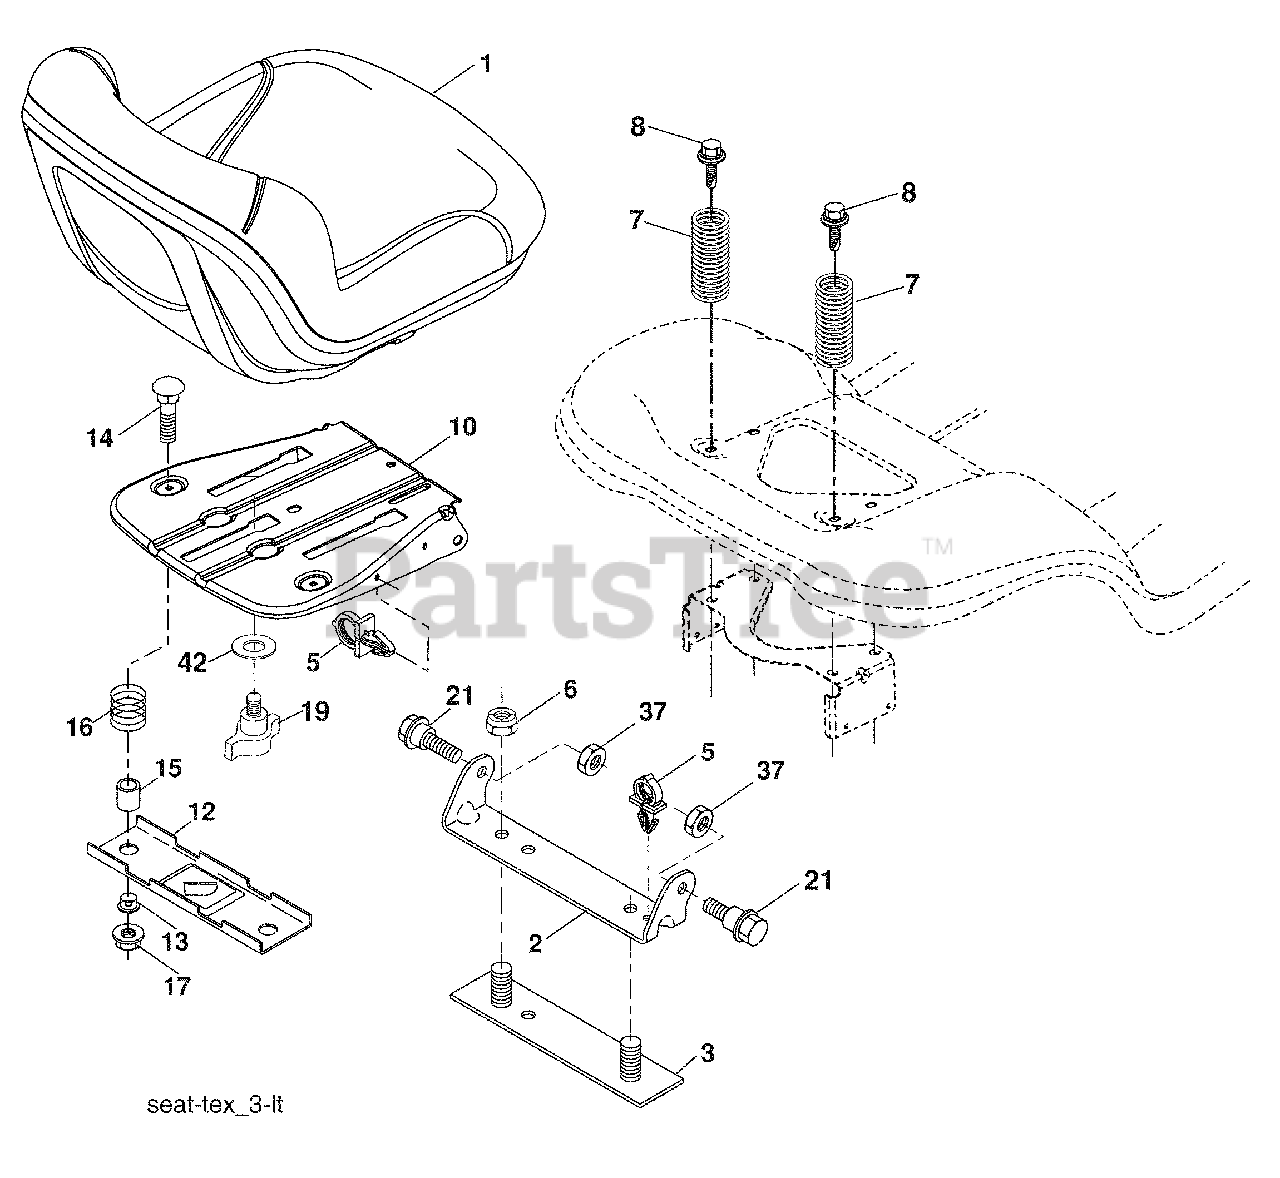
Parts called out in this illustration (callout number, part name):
1	Seat
2	Bracket Pivot Fender
3	Strap, Asm Fender
5	Clip, Push In, Hinged
6	Nut, Lock w/Ins. 3/8-16 unc
7	Spring, Seat Cprsn
8	Bolt 5/16-18 unc x 3/4 w/Sems
10	Pan, Seat
12	Bracket, Seat
13	Bushing Snap
14	Bolt 1/4-20 x 1-1/2
15	Spacer Split
17	Nut lock 1/4 GR 5
19	Knob, Seat
21	Bolt, Shoulder 5/16-18
37	Nut, Lock 5/16-18 unc
